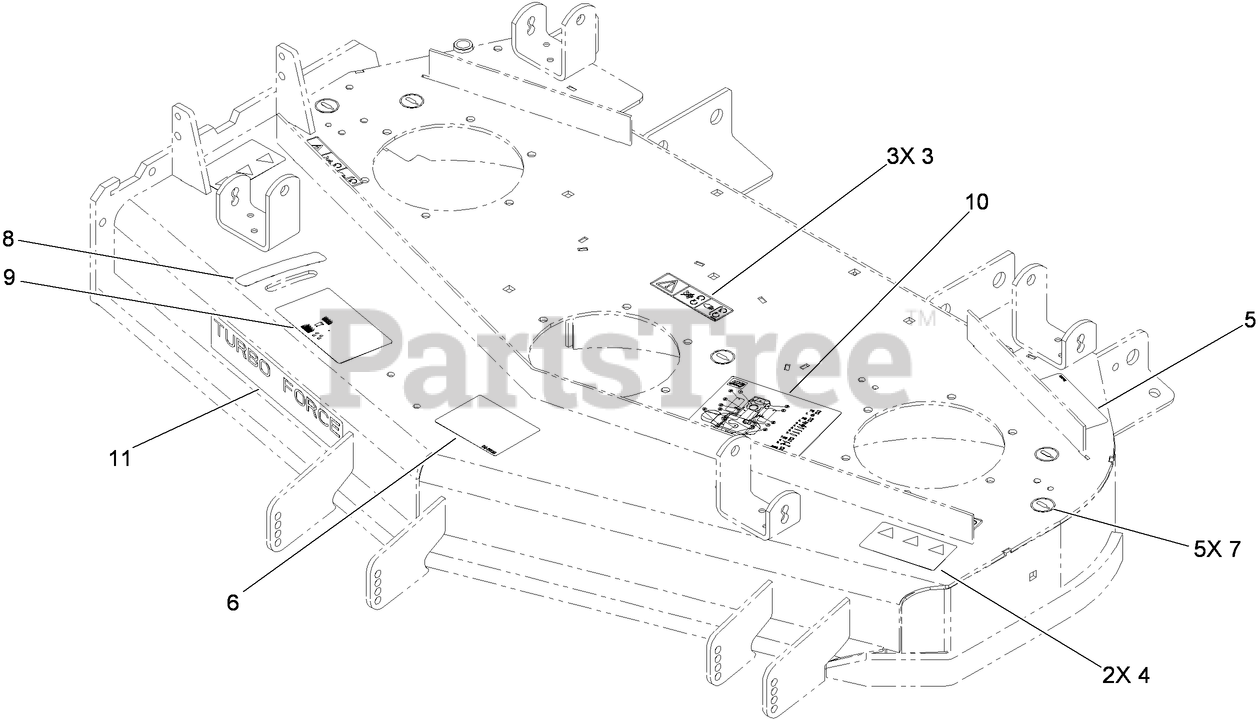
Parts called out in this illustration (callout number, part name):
3	DECAL-MISSING, COVER
4	DECAL-DANGER
5	DECAL-TORQUE, BLADE BOLT
6	DECAL-ANTI SCALP
7	DECAL-GREASE
8	DECAL-SETTING, BAFFLE
9	DECAL-ADJUSTMENT, BAFFLE
10	DECAL-SERVICE AID
